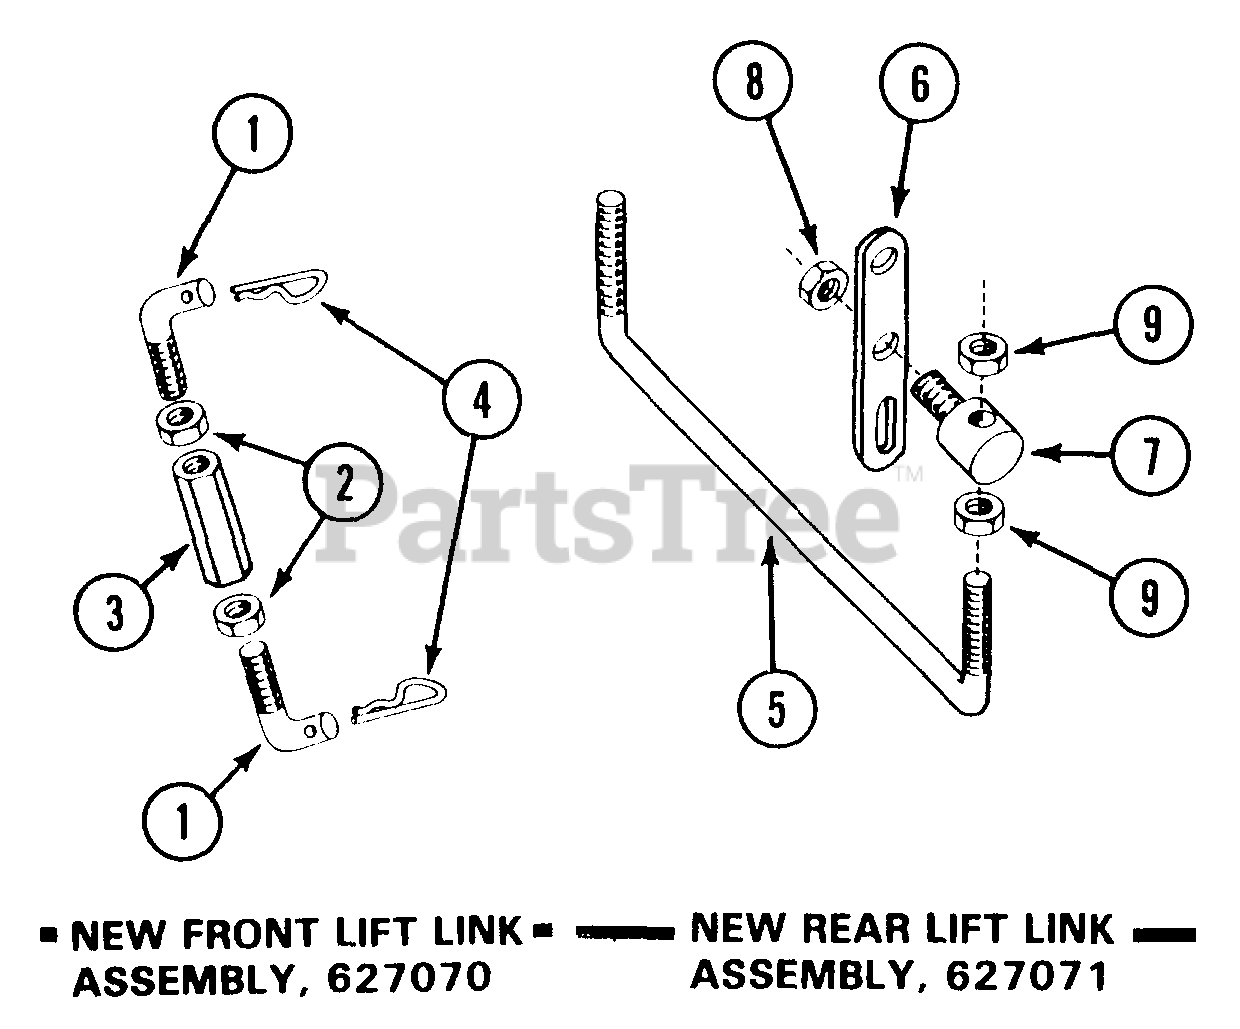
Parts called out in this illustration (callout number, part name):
1	LINK - FRONT LIFT
2	NUT-LK .375-16
3	NUT-CUPLG .375-16 PL
4	PIN-HAIR INT .08X.38X1.42 YWZC
5	ROD - REAR LIFT
6	LINK - REAR LIFT
7	ROD PIVOT
8	NUT-LK .312-18 GR A PL
9	NUT-LK-JAM-CTR .375-16 PL
